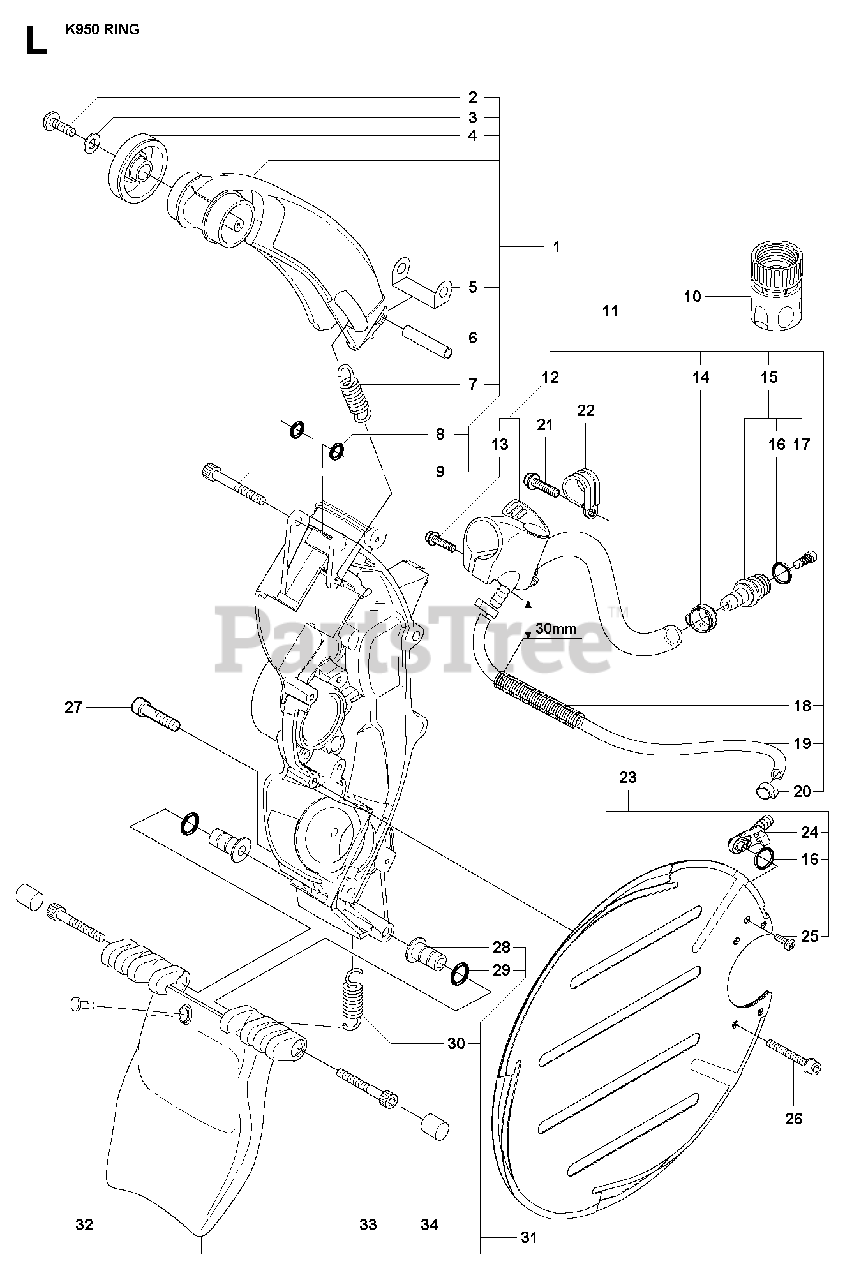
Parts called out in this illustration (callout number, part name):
1	SPRAY GUARD ASSYIncl. 2, 3 - 9
10	SPACING TUBE
11	DRAW SPRINGIncl. 12, 14 - 15, 18 - 20
14	COUPLER
18	HOSE CLAMP
19	NIPPLE
20	O-RING
22	PROTECTIVE SPRING
24	HOSE CLAMP
29	SCREW CRPANT
30	SCREW IHSCM
31	SCREW IHSCMIncl. 28 - 30, 32 - 34
